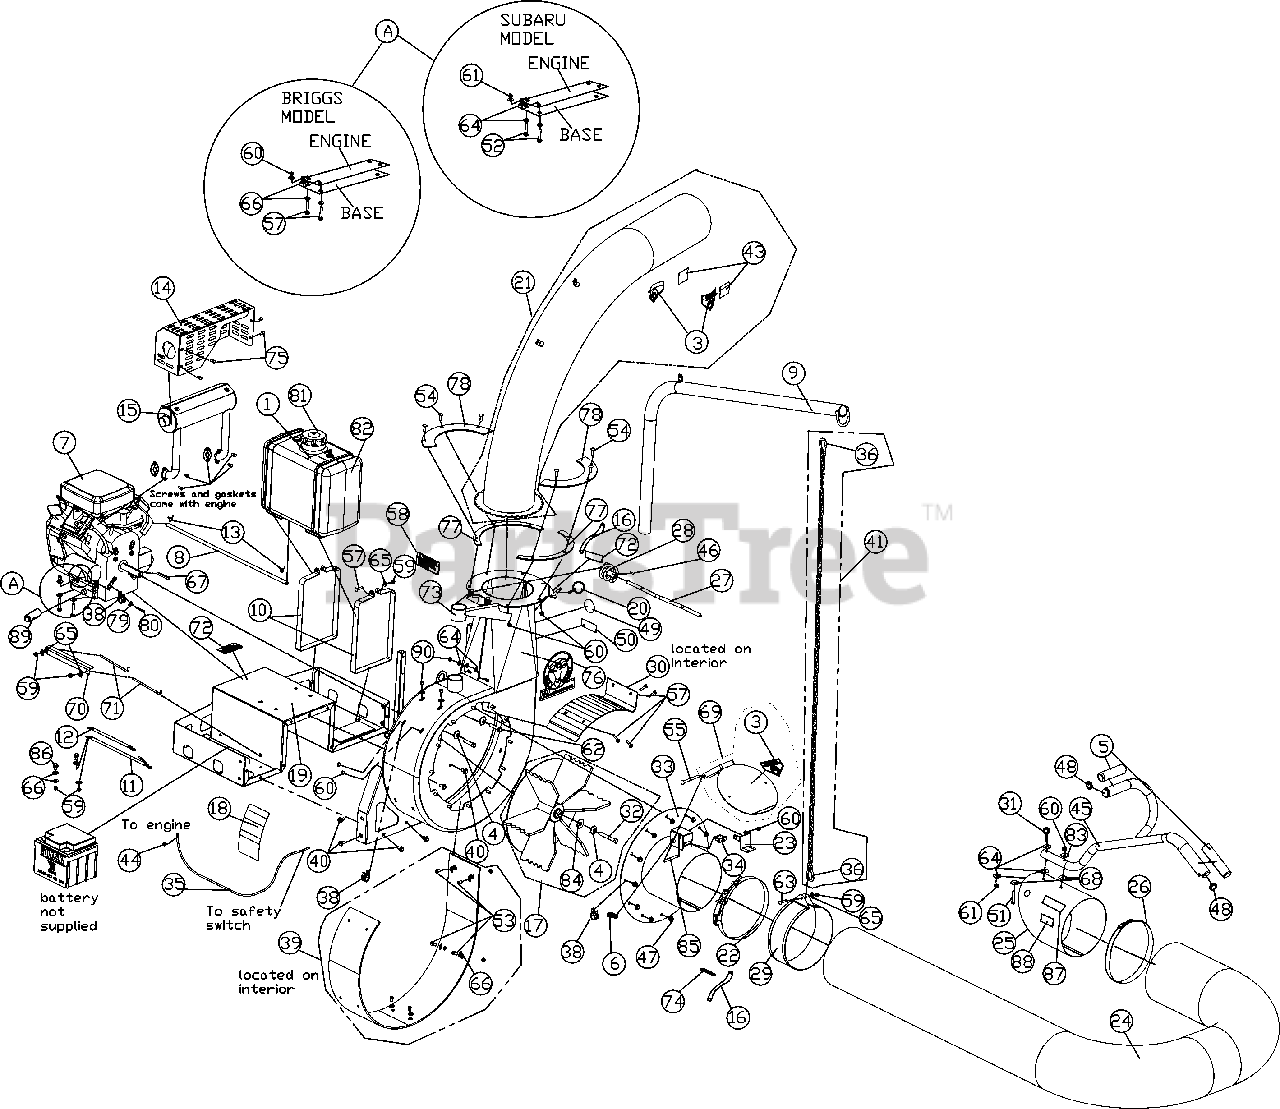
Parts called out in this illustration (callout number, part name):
1	LABEL WARNING EXPLOSIVE FUEL
3	LABEL OPEI WARNING
4	WASHER TWISTED LOCK 7/16"
5	GRIP 1 1/4 ID X 9.5 LONG
6	STRAIN RELIEF HEYCO 1244
7	ENGINE 18 HP VANGUARD
8	LINE FUEL DL
9	TUBE BOOM ARM DL
10	CLAMP GAS TANK
11	CABLE BATTERY RED 26"
12	CABLE BATTERY BLACK 10"
13	CLAMP FUEL LINE
14	EXHAUST GUARD
15	EXHAUST VANGUARD
16	LANYARD 10" PLASTIC
17	IMPELLER DL
18	LABEL DL INSTRUCT/WARN
19	BASE ENGINE ASSY DL
20	LYNCH PIN
21	ELBOW ASSY DL
22	CLAMP QUICK RELEASE 10"
23	LEVER HOSE SWITCH
24	HOSE 10" X 10' INTAKE
25	NOZZLE INTAKE 10" FORMED
26	CLAMP HOSE 10"
27	SHAFT GEAR WORM
28	GEAR WORM
29	BAND HOSE BOOM 10" FORMED
30	CUT OFF LOADER
32	SCREWCAP 7/16-20X3 1/2" GR.8 WITH PATCH [TORQUE 55-60 ft.lb.]
33	INTAKE HOUSING DL 10"
34	PLUNGE SWITCH
35	HARNESS WIRE DL
36	HOOK SNAP SAFETY
38	CLAMP FUEL HOSE LINE
39	INTERIOR LINER
40	WASHER FACE BOLT
41	CHAIN HANG HOSE DL
43	LABEL FLYING DEBRIS
44	WIRE TAP IN
45	HANDLE NOZZLE
46	ROLL PIN .1875 X 0.875
47	NUT WASHER FACE
48	PLUG TUBE INSERT 1.25 OD
49	LABEL EAR EYE BREATHE
50	LABEL READ
51	SCREWCAP 5/16-18 x 2
52	PART NOT APPLICABLE ON THIS MODEL
53	BUTTON HEAD 5/16-18 X 3/4
54	CARRIAGE BOLT 5/16x18x1
55	BOLT CARR. 5/16 - 18 x 3 1/2
56	CARRIAGE BOLT 3/8x16x1
57	CARRIAGE BOLT 1/4-20 X 1 3/4
58	LABEL WARNING ENGINE OVERHEAT
59	NUT LOCK 1/4"-20 HEX Z/P
60	NUT LOCK 5/16-18
61	NUT LOCK 3/8
62	SCREWCAP 7/16-14 X 2 GR 5 W/ PATCHLOCK
63	SCREWCAP 1/4-20 X 3" ZP
64	WASHER FLAT 3/8
65	WASHER 1/4 SAE
66	WASHER 5/16 SAE ZP
67	KEY 1/4" SQ X 2 3/4"
68	WASHER 5/16 FENDER
69	DOOR FLAPPER INTAKE DL 10"
70	BRACKET BATTERY DL
71	ROD BATTERY HOLD DOWN
72	LABEL WARNING SECURE
73	HOUSING ASSY DL
74	SAFETY PIN
75	SCREW 1/4-20 X 5/8 HWH
77	PLATE CLAMP SPLIT
78	PLATE CLAMP HALF
79	WASHER LOCK 5/16
80	SCREWCAP 5/16-24 X 3/4
81	CAP TANK FUEL 6 GAL
82	TANK FUEL 6 GAL
83	PART NOT APPLICABLE ON THIS MODEL
84	WASHER 1.5 OD X .453 ID X .5
85	SPACER 3/8 X 2 1/2
86	SCREWCAP 1/4-20 x 3/4
87	LABEL NOZZLE SECURE
88	LABEL WARNING NOZZLE
89	VALVE OIL DRAIN
90	NUT LOCK 5/16-18 ZP
